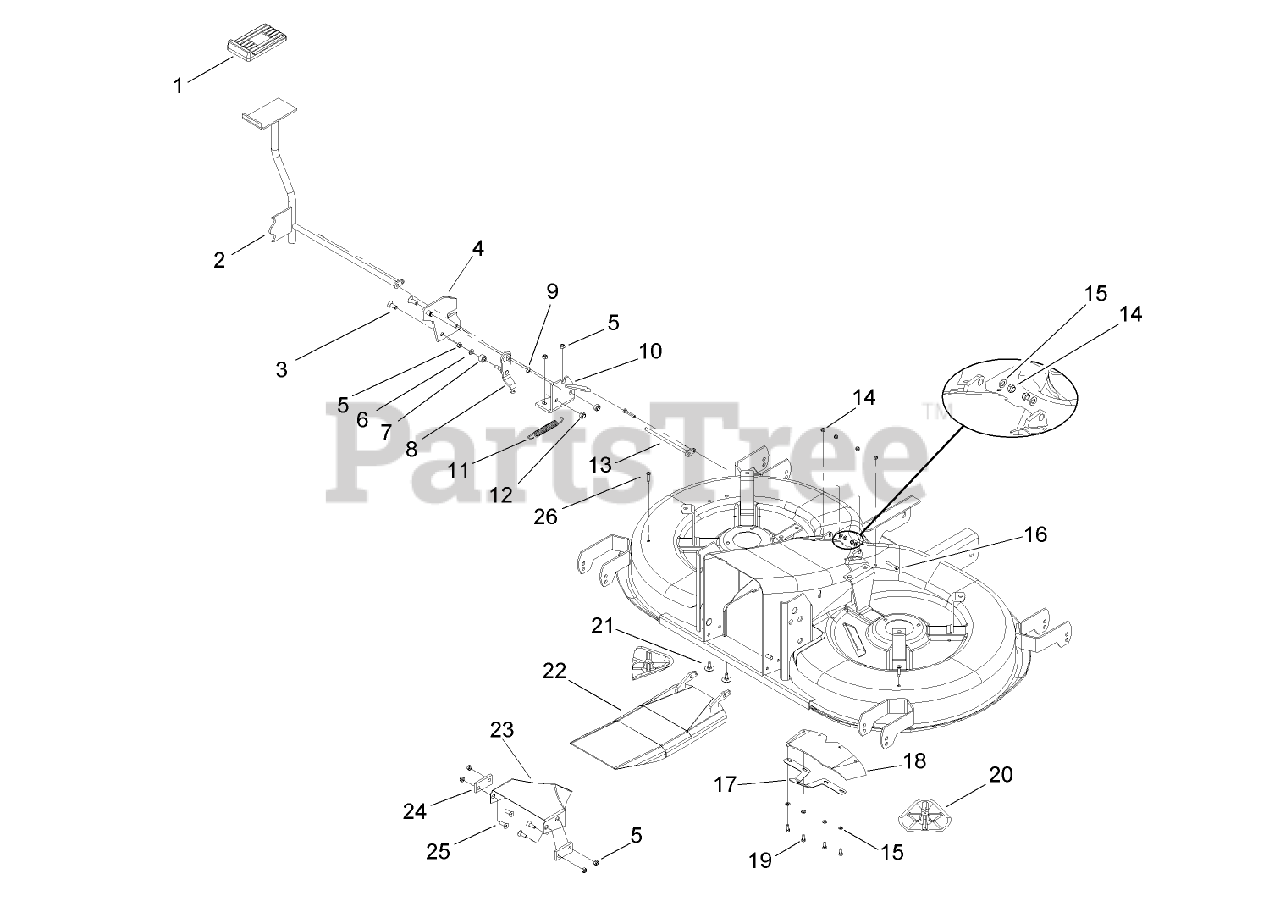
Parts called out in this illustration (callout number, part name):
1	Cover-Lever, FOOT
2	Lever-Foot
3	SCREW-HSFH
4	Plate-Stop
5	NUT-LOCK
6	WASHER-FLAT
7	Roller
8	Lever-Spring
9	RING-LOCKING
10	Bracket-Mounting
11	Spring
12	NUT
13	Rod-Door, Mulch
14	NUT-LOCK
15	WASHER
18	Gasket-Door, Mulch
19	Screw-HH
20	Kicker
21	SCREW-CARR
23	Baffle-Center
24	PLATE-BAFFLE, CENTER
26	SCREW-TAP, PPH
